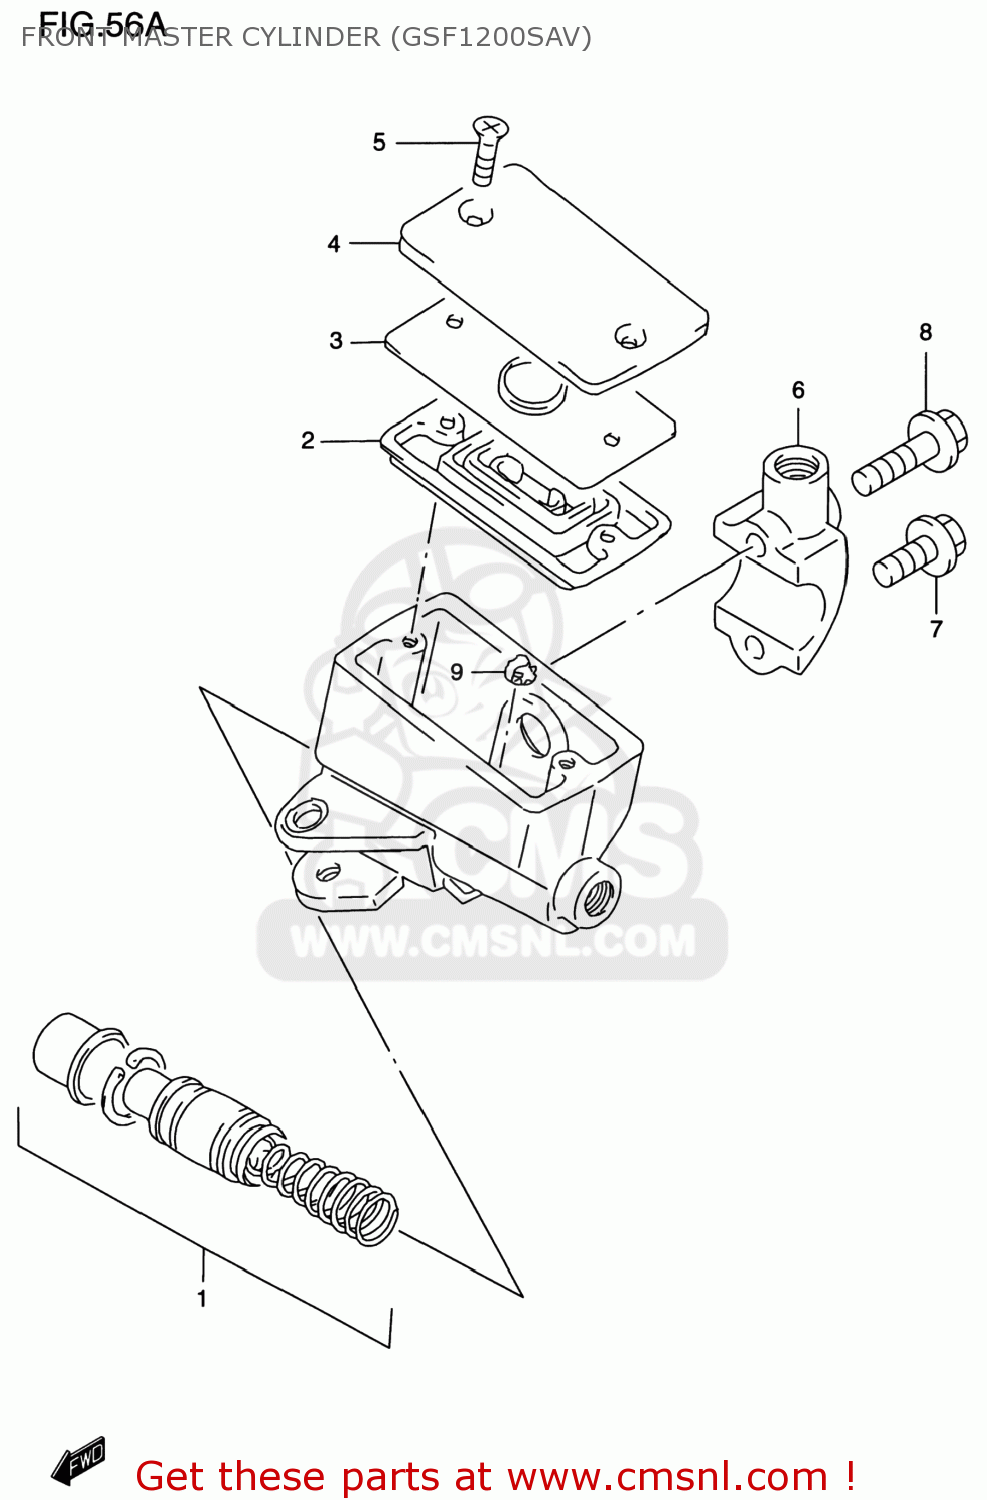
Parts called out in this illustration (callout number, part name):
1	PISTON & CUP SET
2	3
3	PLATE,DIAPHRAGM
4	CAP
5	SCREW
6	HOLDER
7	BOLT(6X25)
8	BOLT(6X38)
9	PROTECTOR
